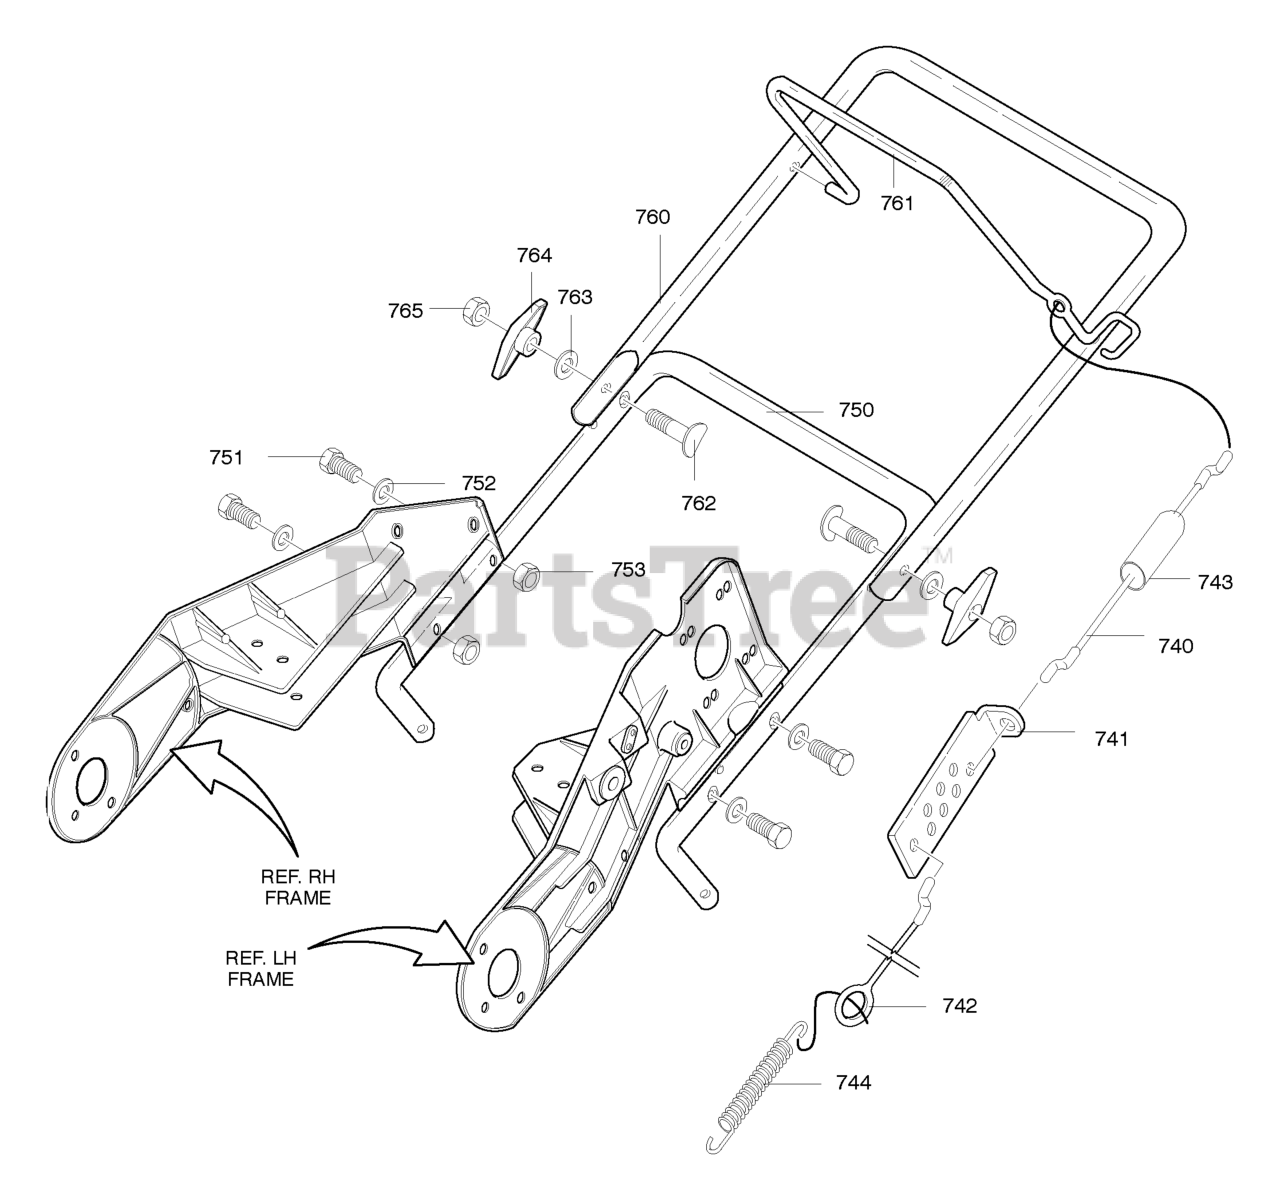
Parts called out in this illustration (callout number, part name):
740	CABLE, UPPER CONTROL
741	LF BRKT, CABLE ADJ
742	CABLE, LOWER CONTROL
743	BOOT, CLUTCH SPRING
744	SPRING, EXTENSION
750	HANDLE, LOWER
751	SCREW, 1/4-20X1.25
752	WASHER, FLAT.
753	NUT, 1/4-20
760	HANDLE, UPPER
761	BAIL, CONTROL
762	BOLT, 5/16-18X2.OO
763	WASHER, FORM
764	KNOB, T 3.00 WD PLAS BLA
765	NUT, 5/16-18 REGHEX
